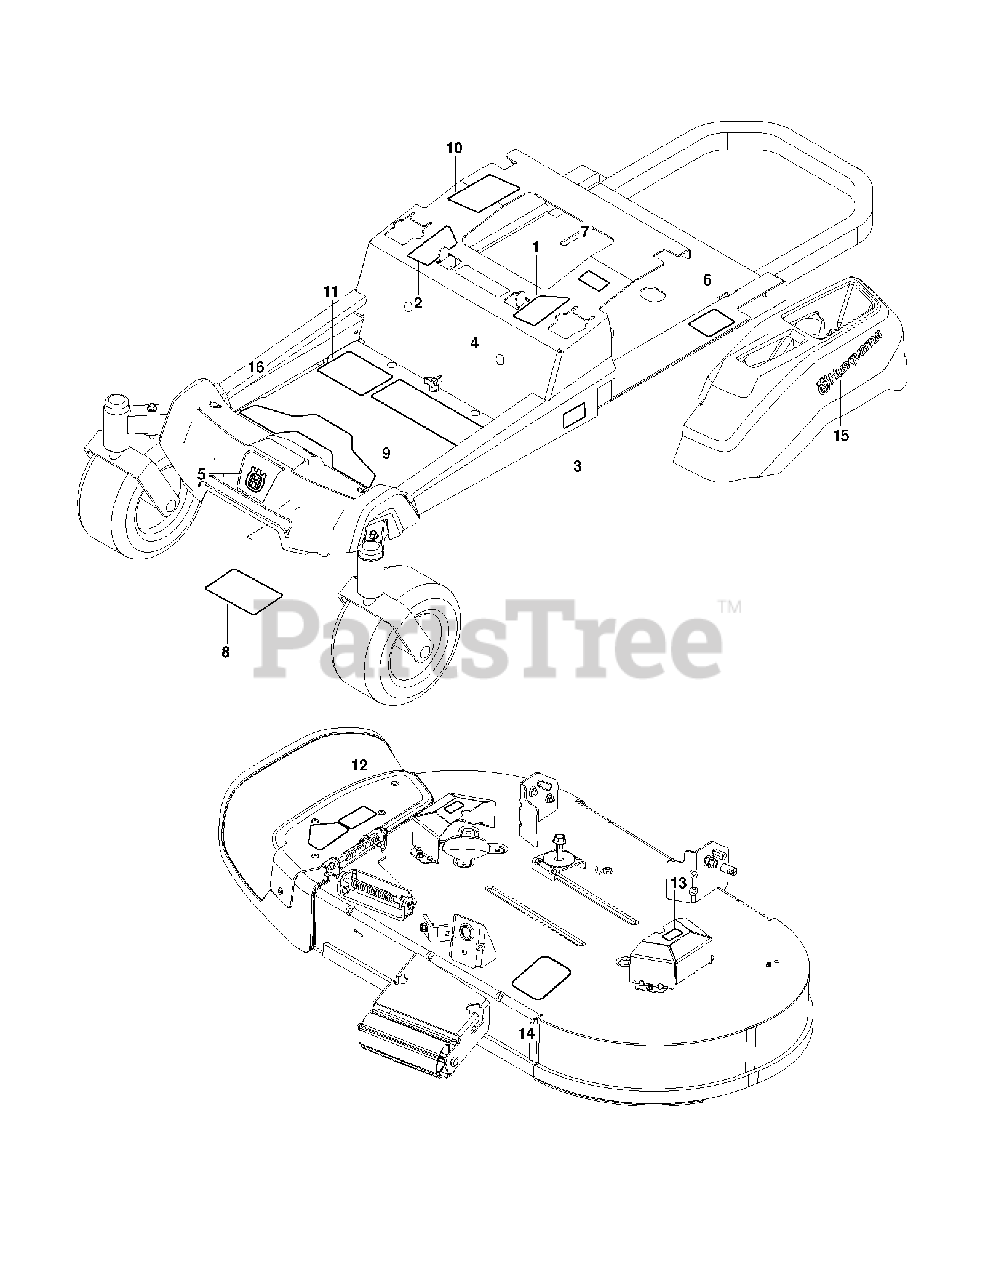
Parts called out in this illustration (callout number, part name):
1	DECAL.ZTR.RZ.THRTL/PRKBRK.V2.L
2	DECAL.ZTR.RZ.THRTL/PRKBRK.V2.R
3	DECAL.ZTR.SIDRAIL.Z242F.HUS
4	EURO DECAL-BATTERY WARNIN6
5	DECAL.BADGE.55MM.CROWNH.HUSQ
6	DECAL, DO NOT TOW
7	DECAL, EXITING MOWER
8	DECAL, SERVICE
9	DECAL, SAFETY WARNING
10	DECAL.WARNING.CUST.RESP.E85.
11	DECAL.ZTR.STRTNGINST.REMOTECHK
12	DECAL.TRACT/ZTR.DECKWARN.JONS
13	DECAL.DECK.6MIL.EURO.NOSTEP
14	DECAL, BELT ROUTING
15	DECAL.HUSQVARNA.210MM
16	PAD.RZ.FOOTREST.PLATE
